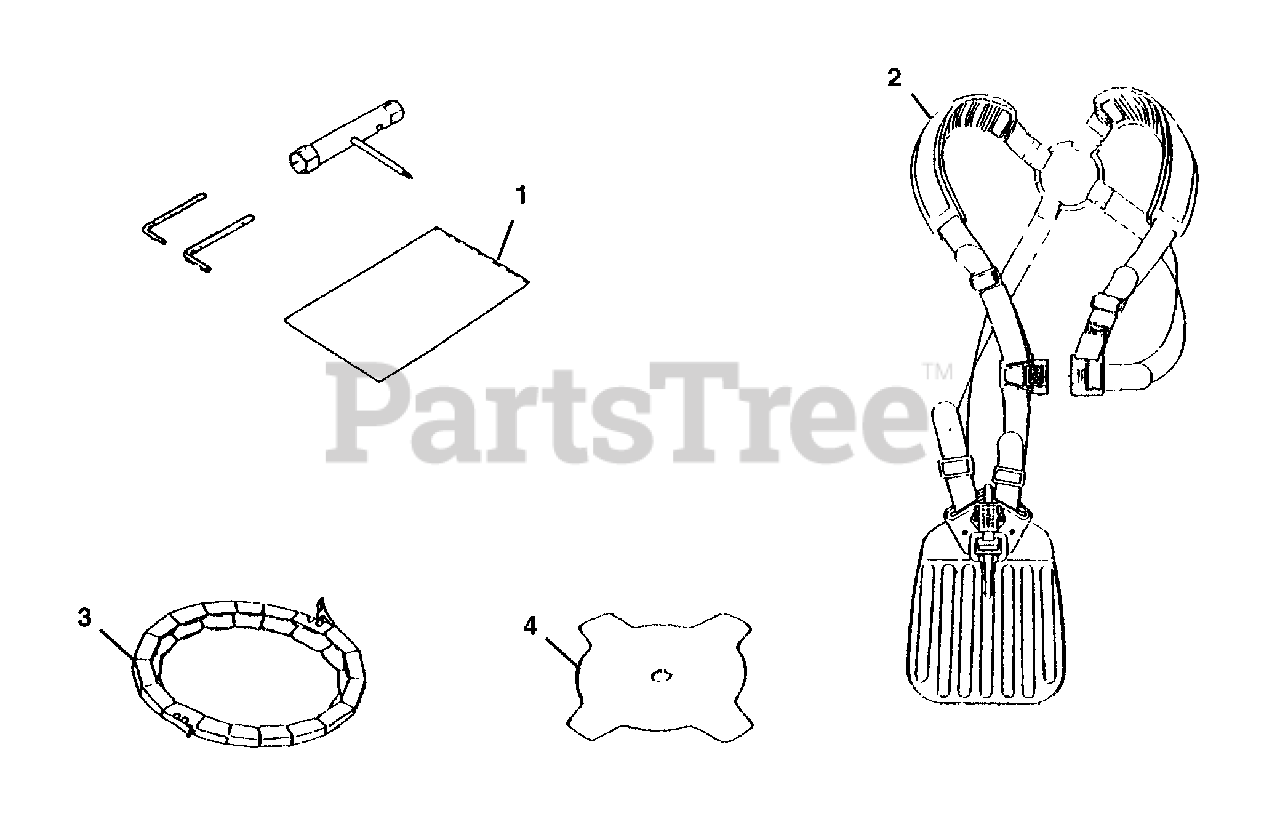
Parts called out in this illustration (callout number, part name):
1	TOOL KIT
2	SHOULDER HARNESS
3	BLADE COVER
4	BLADE CUTTER
